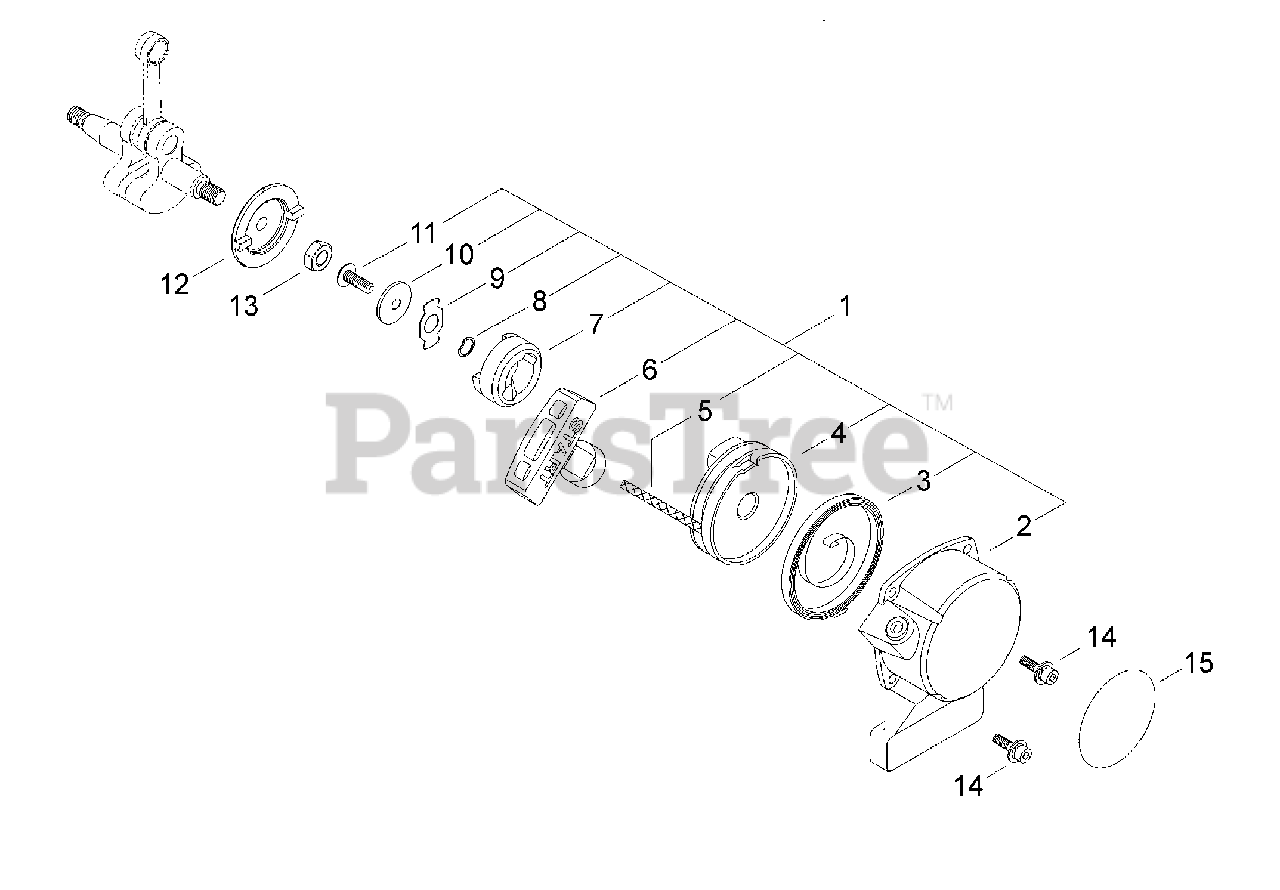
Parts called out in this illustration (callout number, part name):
1	STARTER ASSY, RECOIL
2	CASE, RECOIL STARTER
3	SPRING, RECOIL
4	REEL, ROPE
5	ROPE, STARTER
6	GRIP, STARTER
7	PAWL, STARTER
8	WASHER, WAVE
9	RETAINER
10	WASHER 5 MM
11	SCREW 5 MM
12	PULLEY, STARTER
13	NUT M8×1
14	BOLT M4×16
15	LABEL, RECOIL C4
